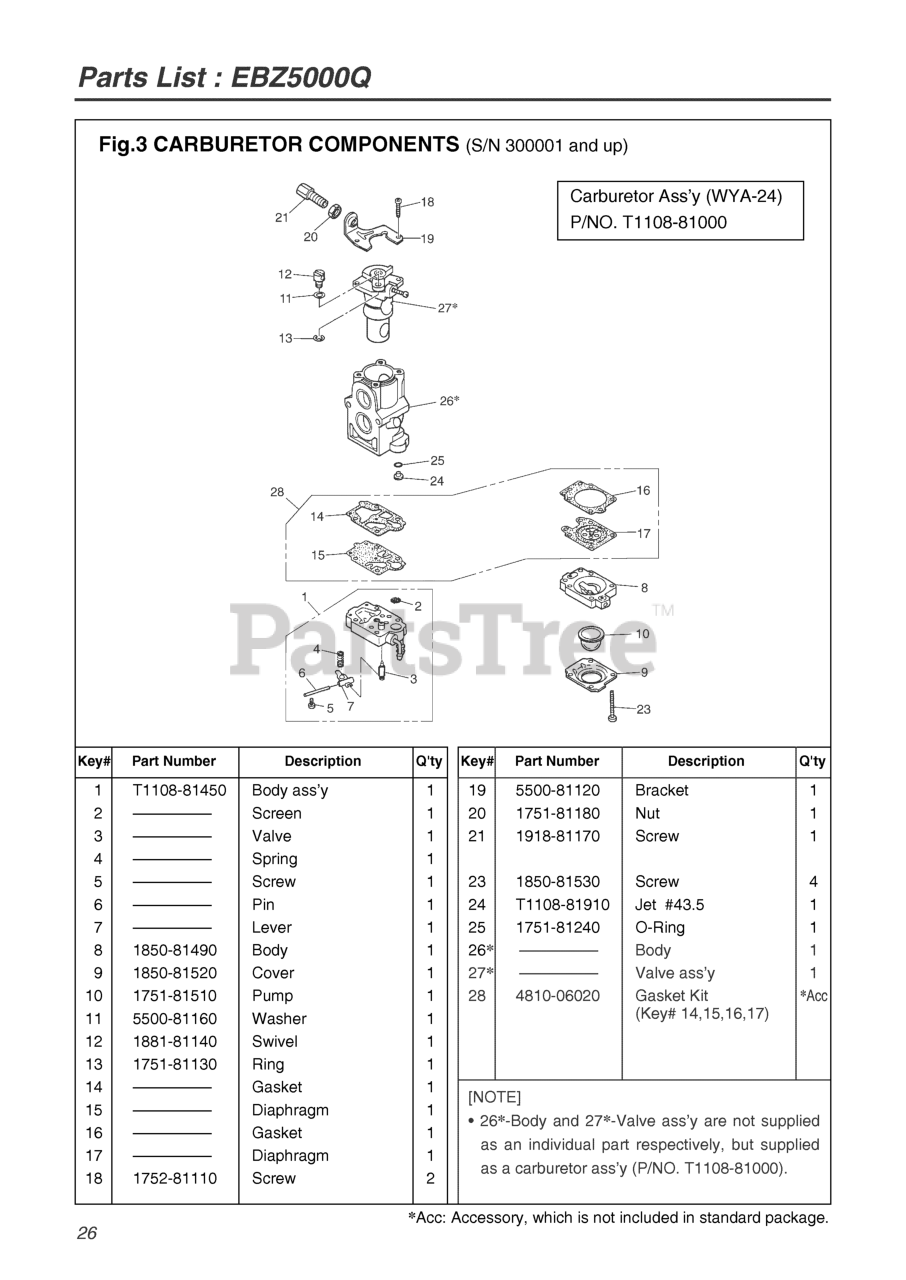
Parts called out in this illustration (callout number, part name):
1	BODY ASSY.
2	SCREEN
3	VALVE, INLET
5	SCREW
6	PIN
7	LEVER
8	BODY, PURGE
9	COVER, PUMP
10	PUMP, PRIMING
11	WASHER
12	SWIVEL
13	RING
14	GASKET
15	DIAPHRAGM
16	GASKET
17	DIAPHRAGM
18	SCREW
20	NUT, CABLE ADJUSTER
21	SCREW, CABLE ADJUSTER
23	SCREW
24	JET 43.5
25	RING, O
26	BODY
27	VALVE ASSY
